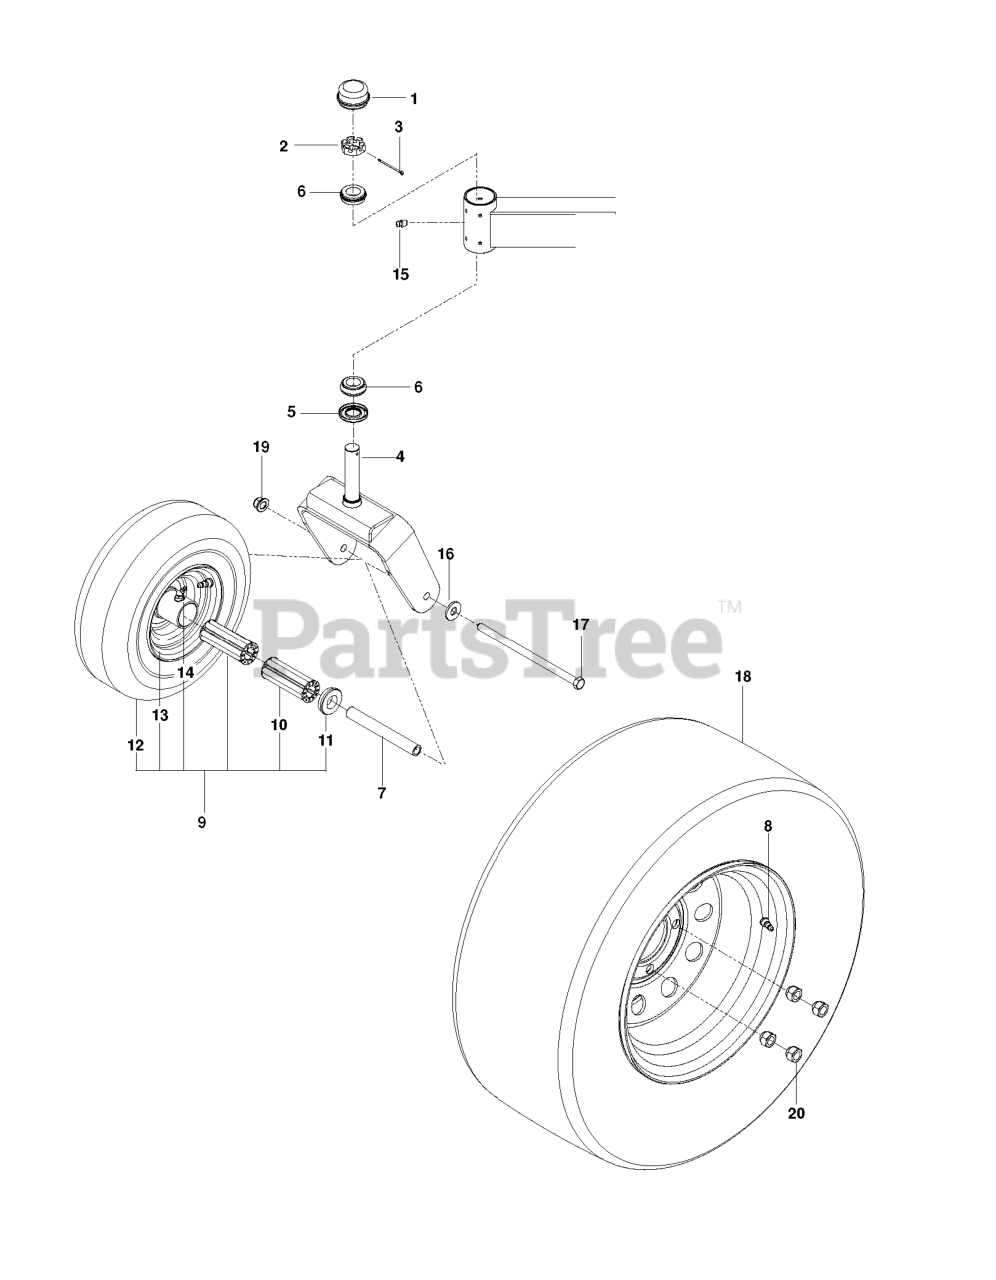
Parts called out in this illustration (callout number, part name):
1	GREASE CAP
2	NUT 1"C HEX SLOTTED
3	COTTER PIN 1/8 X 2
4	YOKE.CASTER.ORANGE
6	TAPERED ROLLER BRG
7	SPACER, PIVOT
8	VALVE STEM TR-412
9	TIRE.ASSEM.CASTER.13X6.5-6.SIL
10	ROLLER BEARING-CAGED 3 1/4'
11	BEARING RETAINER
12	TIRE.13X6.50-6.4.PLY
13	WHEEL.6X4.50.CASTER.SILVER
14	ZERK
15	ZERK
16	WASH USS FLAT 1/2
17	HEX SCREW 1/2-13 X 9.5 GR5
18	TIRE.ASSEMBLY.23X9.50-12
19	NUT, 1/2-13 HEX FLG NYLOC ZD
20	LUG NUT 1/2F
